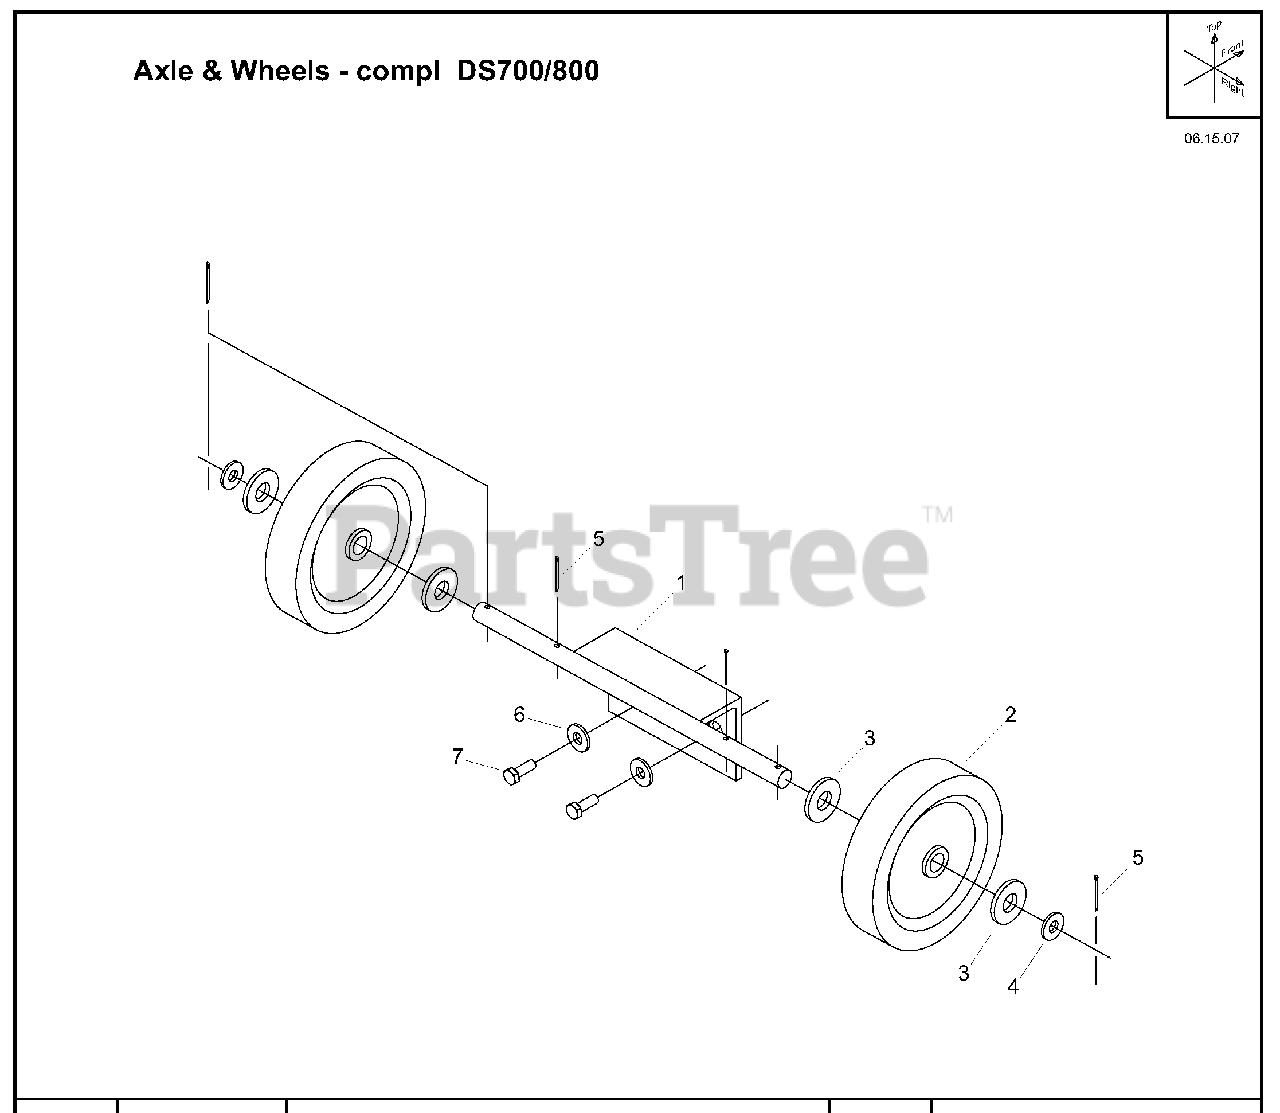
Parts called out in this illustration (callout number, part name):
1	Bracket, Axle
2	Wheel, 5" Dia
3	Washer, Flat 5/8" SAE
4	Washer, Flat 5/8"
5	Pin, Cotter .125 x 1.5
6	Washer, Flat 1/2" SAE
7	Capscrew, Hex Hd 1/2-13 x 1"
